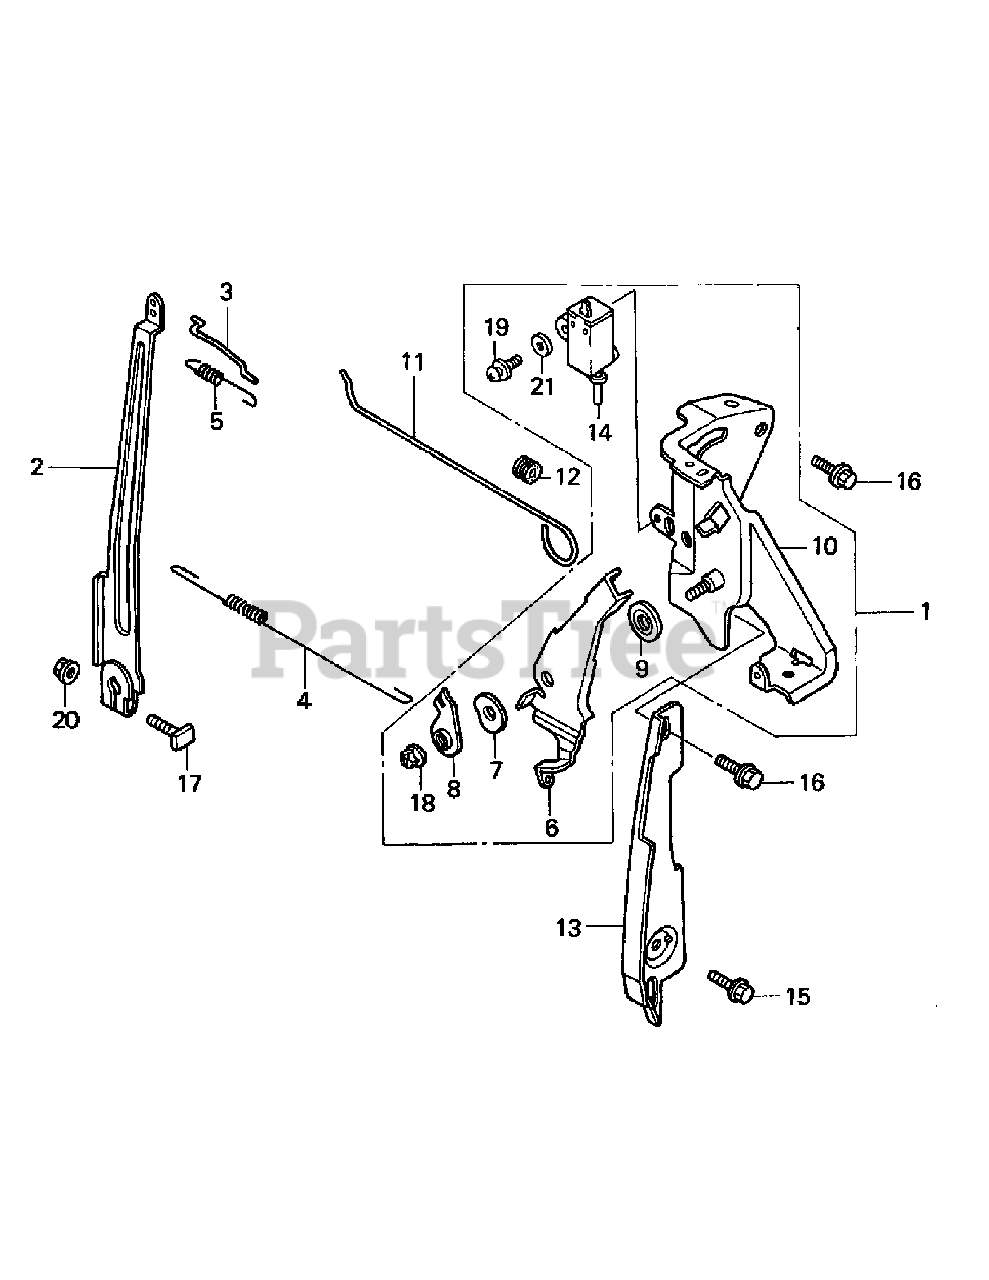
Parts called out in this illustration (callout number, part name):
1	Control Assembly
2	Governor Arm
3	Governor Rod
4	Governor Spring
5	Throttle Return Spring
6	Control Lever
7	Lever Spring
8	Control Lever Washer
9	Control Lever Spacer
10	Control Base
11	Choke Control Rod
12	Choke Rod Grommet
13	Side Plate
14	Engine Stop Assembly Switch
15	Flange Bolt, 6 x 12
16	Flange Bolt, 6 x 14
17	Governor Arm Bolt
18	Self-Lock Nut, 6mm
19	Screw-Washer, 4 x 12
20	Flange Nut, 6mm
21	Plain Washer, 4mm
